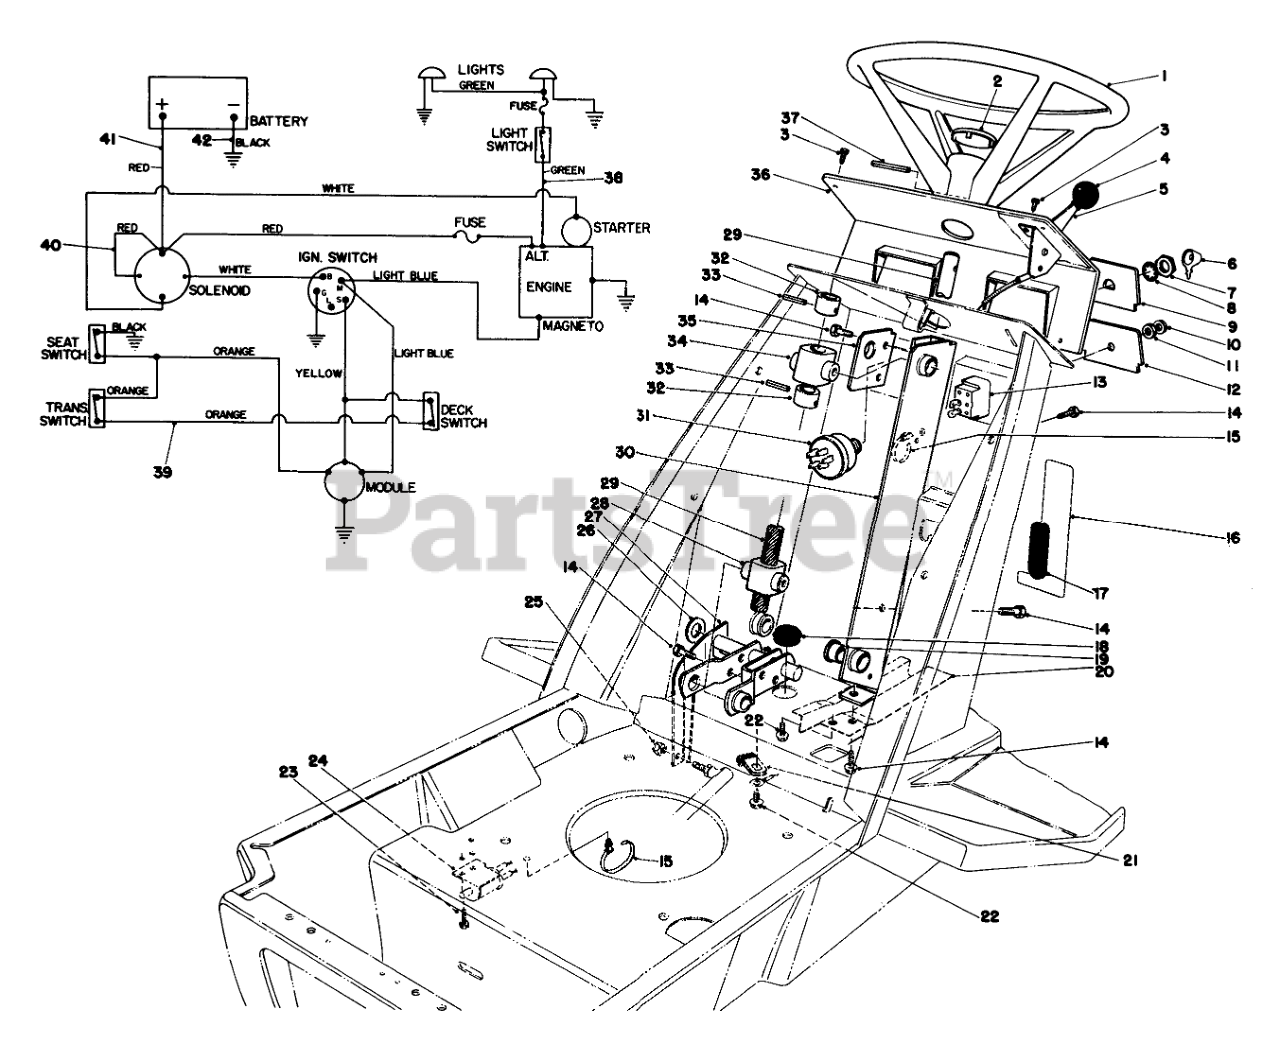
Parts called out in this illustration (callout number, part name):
1	Steering Wheel
2	STEERING WHEEL INSERT
3	SCREW-HWHTF
4	KNOB-CONTROL
5	Throttle Control (Incl. Ref. #4)
6	12 Key
8	WASHER-TOOTH, INTERNAL
9	DASH PANEL INSERT
10	Beveled Facenut
11	Locknut
12	Insert-Dash Panel (Lights) (Model #57360)
13	Light Switch (Model #57360) (Incl. Ref. #10 & 11)
14	Self Tapping Screw
15	Push Mount Tie
16	Decal-Deck
17	Edge Molding
18	Grommet
19	Flange Bearing
20	Shield Wire Harness
21	Clamp
22	Screw Thread Forming
23	Screw Thread Forming
24	Interlock-Deck Switch
25	Locknut
26	Washer
27	Steering Link
28	Spring
29	Shaft-Steering
30	Bracket-Steering
31	Ignition Switch (Incl. Ref. #6-8)
32	Collar-Steering Shaft
33	Roll Pin
34	Spacer
35	Bail Lift Pin
36	Panel-Dash
37	Roll Pin
38	Wire Harness Lights (Model #57360)
39	Wire Harness
40	Handle, R.H.
41	Wire Assembly (Battery to Solenoid)
42	Drive Shaft
